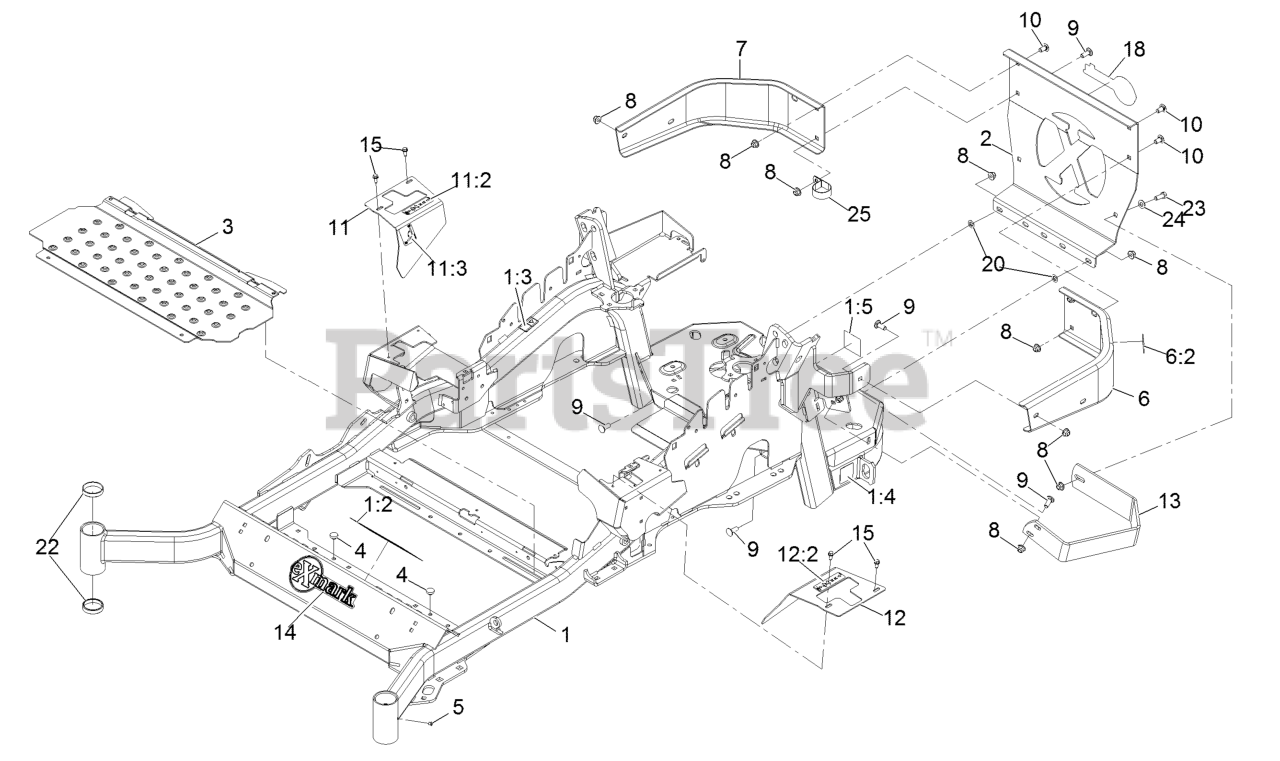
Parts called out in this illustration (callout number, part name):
1	Mainframe ASM
1:2	Decal-Danger
1:3	Decal-Warning
1:4	Decal-Hazard, Pinched Finger
1:5	Decal-Spark Arrester
2	Plate,Rear Guard
6	LH Bumper ASM
6:2	Decal-Warning
7	Bumper-RH
8	Nut-Nyloc 3/8-16 Flg
9	Bolt-Carriage 3/8-16 X 1
10	Bolt-Carriage 3/8-16 X 3/4
11	RH Motion Control Cover ASM
11:2	Decal-Control, Motion
11:3	Decal-Park Brake, CE
12	LH Motion Control Cover ASM
12:2	Decal-Control, Motion
13	Guard-Muffler
14	Decal-Exmark
15	Screw-HWH 1/4-20 X .62
18	Decal-Exmark Logo
20	Nut-Push 3/8-16
22	Cup-Bearing Tapered Roller
23	Screw-HH 3/8-16 X 1
24	Washer-3/8 SAE
